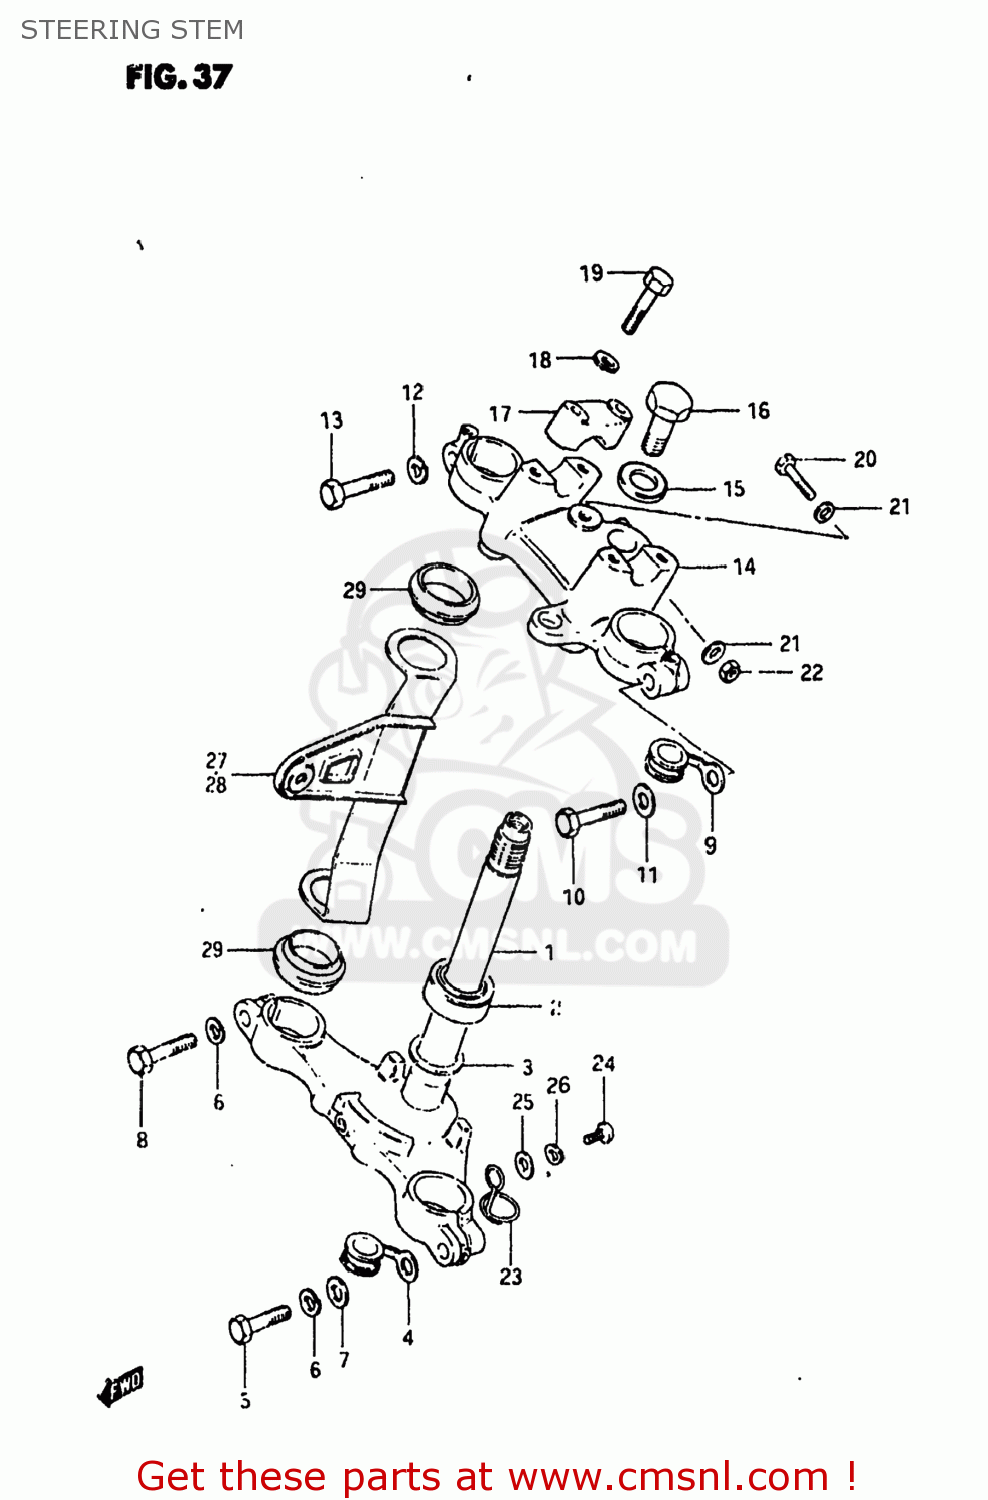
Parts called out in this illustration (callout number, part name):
1	STEM,STEERING
2	BEARING
3	WASHER,THRUST
4	CLIP,CABLE
5	BOLT 12X45
6	WASHER,LOCK 12
7	WASHER
8	BOLT
9	CLAMP,METER CABLE
10	BOLT 10X40
11	WASHER
12	LOCK WASHER
13	BOLT 10X40
14	HEAD,STEERING STEM
15	WASHER
16	BOLT,STEERING STEM HEAD
17	HOLDER,HANDLEBAR
18	LOCK WASHER
19	BOLT
20	BOLT 8X50
21	WASHER
22	NUT
23	CLIP
24	SCREW
25	WASHER
26	LOCK WASHER
27	BRACKET,HEADLAMP,RIGHT
28	BRACKET,HEADLAMP,LEFT
29	GASKET
